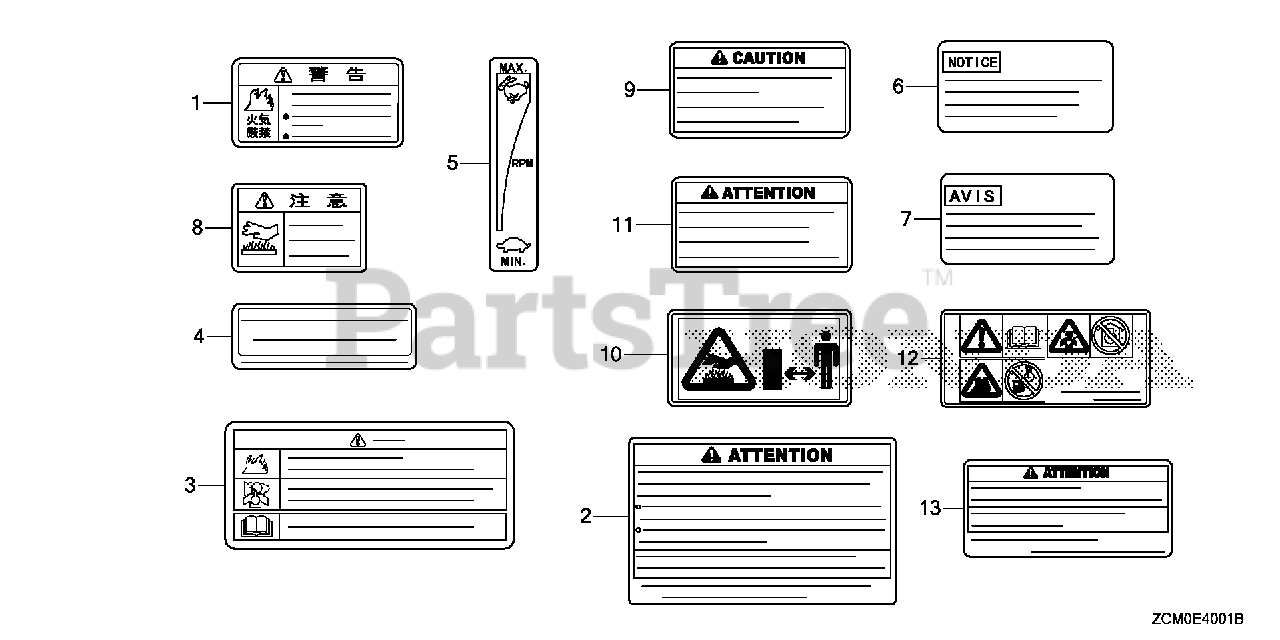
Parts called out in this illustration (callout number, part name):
5	MARK, THROTTLE INDICATION
9	MARK, EX. CAUTION (ENGLISH)
10	MARK, EX. CAUTION (PICTOGRAPH)
11	MARK, EX. CAUTION (FRENCH)
12	MARK, OPERATOR CAUTION (PICTOGRAPH)
13	MARK, OPERATOR CAUTION (FRENCH)
